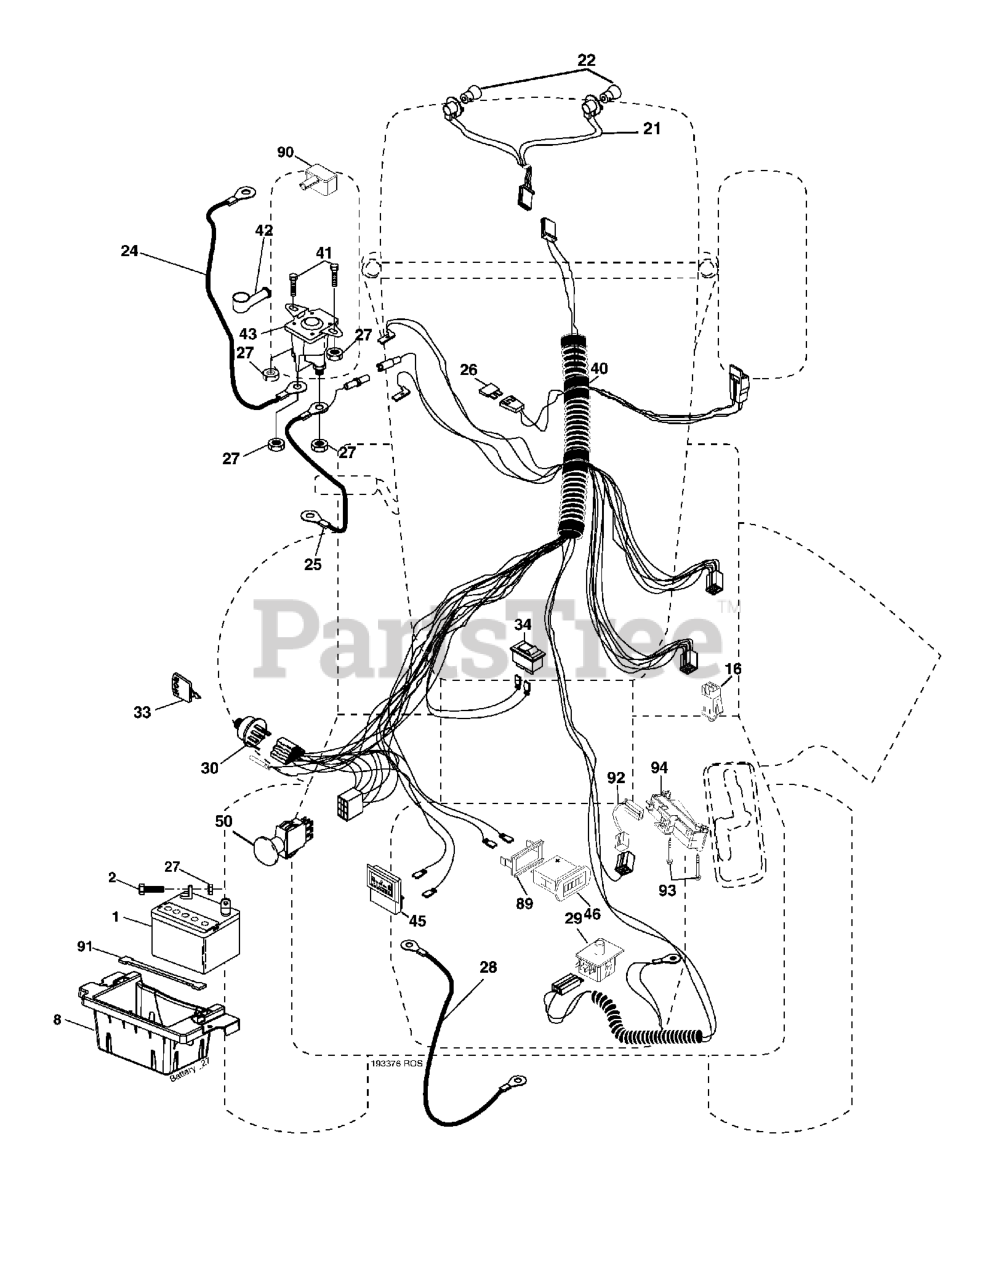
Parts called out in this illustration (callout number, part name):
1	BATTERY 12V .35 AMP
2	BOLT.HEX.1/4.X.3/4.DICHROMATE
8	BOX.BATTERY.MOUNT.FRONT.LT
16	SWITCH INTERLOOK PUSH-IN
21	HARNESS ASSY LIGHT
22	LIGHTBULB
24	BATTERY CABLE GT
25	CABLE BATTERY 6 GA 22" W/16W
26	FUSE 20AMP
27	NUT
28	CABLE GROUND 6 GA 21" 90T BLK
29	SWITCH.SEAT.DP W/RAMPS
30	SWITCH.IGN.DELTA.W.LGH.ROS
33	KEY MLD GEN DELTA
34	SWITCH LT
40	HARNESS.IGN.ELECT.STL
41	SCREW
42	TERMINAL COVER
43	SOLENOID
45	AMMETER
46	HOUR METER
50	RP.SWTICH.PTO.8.TERMINAL
89	BRACKET SNAP-IN HOURMETER
90	COVER TERMINAL
91	STRAP.BATTERY.MOUNT.FRONT(2 2)
92	HARNESS.PIGTAIL.REVERSE.SWITCH
93	SCREW.PLASTITE
94	MANUAL.O.SP185H42STB.E
